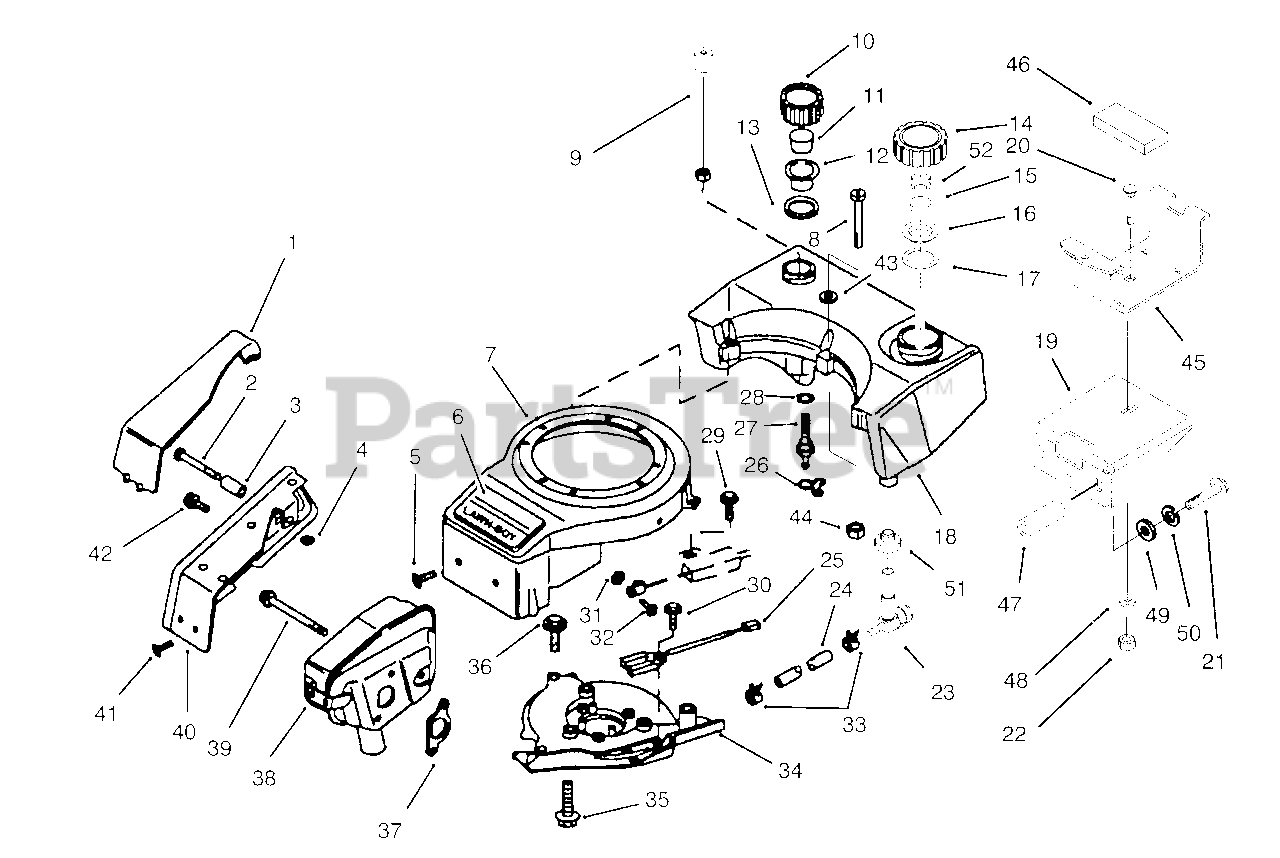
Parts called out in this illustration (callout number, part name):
1	Cover-Muffler
2	Screw-Muffler Guard
3	Spacer-Muffler Guard
4	Pushnut
5	Screw-Shroud
6	Applique
7	Shroud (Incl. Ref. No. 6)
8	Screw-Fuel Tank
9	Switch-Low Oil
10	Oil Cap (Incl. Ref. #11-13)
12	Cover-Baffle
14	Fuel Cap Assembly (Incl. Ref. No.15-17)
16	Cover-Baffle
18	Tank-Fuel/Oil
19	Bracket-Fuel Tank
20	Bolt-Carriage
21	Screw-Socket Hd.
22	Nut-Lock
23	Shut-OffValve-Fuel
24	Fuel Line
25	Switch-Brake Interlock
26	Clamp-Oil Hose
27	Assembly-Oil Fitting (Incl. Ref. No. 28)
30	Screw-Interlock Switch
31	Nut-Lock
33	Clamp-Fuel Line
34	Plate-Engine Mounting
35	Screw-Mtg. Plate/Housing
36	Screw-Mtg Plate/Housing
37	Gasket-Exhaust
38	Muffier
39	Screw-Muffler
40	Muffler Guard (Incl. Ref. #1-4)
41	Screw-Muffler Guard
42	Screw-Muffler Guard
43	Washer-Flat
44	Nut-Lock
45	Saddle-Fuel Tank
46	Mount-Fuel Tank
48	Washer-Flat
49	Washer-Flat
50	Washer-Lock
51	Bushing
